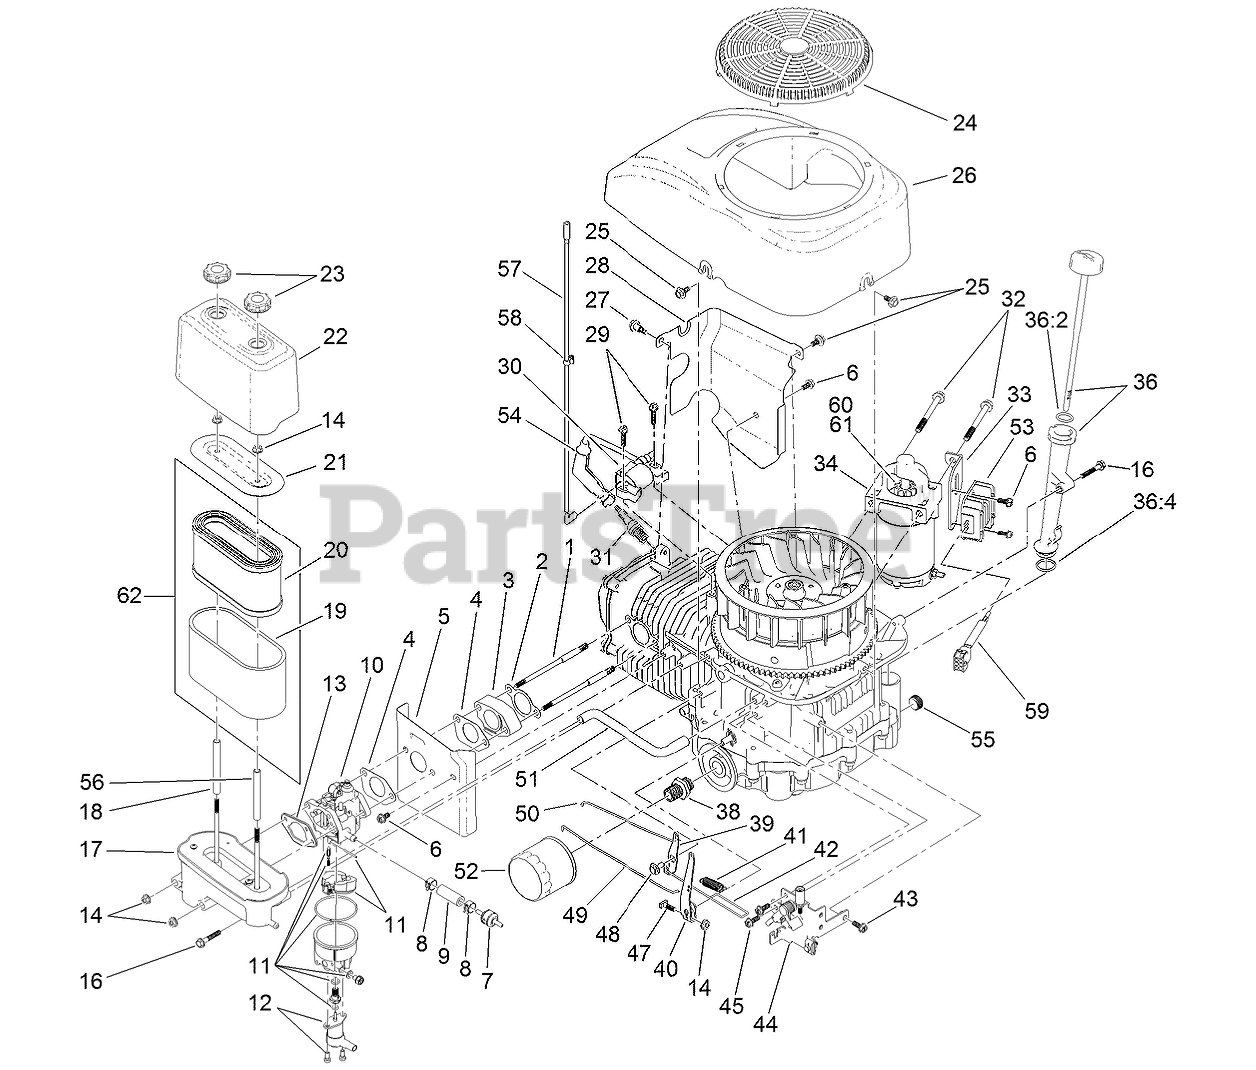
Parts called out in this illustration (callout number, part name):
1	STUD-MOUNT, CARBURETOR
2	GASKET-CARBURETOR
3	INSULATOR-CARBURETOR
4	GASKET-CARBURETOR
5	SHIELD-HEAT
6	SCREW-HHF
7	FILTER-FUEL
8	CLAMP-FUEL LINE
9	LINE-FUEL
10	CARBURETOR KIT
11	CARBURETOR REPAIR KIT
12	SOLENOID KIT
13	GASKET-BASE, FILTER
14	NUT-FLANGE
16	SCREW-HHF
17	BASE-FILTER, AIR
18	SPACER-FILTER, AIR
19	PREFILTER
20	FILTER-AIR
21	RETAINER-AIR FILTER
22	COVER-FILTER, AIR
23	NUT-SPEED
24	SCREEN-STATIONARY
25	SCREW-SHOULDER, HH
26	SHROUD-FAN
27	SCREW-SHOULDER, HH
28	SHIELD
29	SCREW-HHF
30	COIL-IGNITION
31	PLUG-SPARK
32	SCREW-HHF
33	BRACKET-STARTER
34	STARTER-ELECTRIC
36	DIPSTICK AND TUBE ASM (W/O-RING)
36:2	O-RING
36:4	O-RING
38	ADAPTOR-FILTER, OIL
39	BELLCRANK-CHOKE
40	Arm-Governor
41	SPRING-GOVERNOR
42	ROD-THROTTLE
43	SCREW-HHF
44	CONTROL-THROTTLE
45	SCREW-HHF
47	BOLT-ARM, GOVERNOR
48	SCREW-SHOULDER, HHF
49	ROD-GOVERNOR
50	ROD-CHOKE
51	TUBE-BREATHER
52	FILTER-OIL
53	REGULATOR-VOLTAGE
54	BOOT-PLUG, SPARK
55	PLUG-DRAIN
56	SPACER-FILTER, AIR
57	WIRE-KILL, IGNITION
58	CLAMP-WIRE
59	HARNESS-WIRE
60	STARTER REPAIR KIT
61	PINION
62	AIR FILTER KIT
